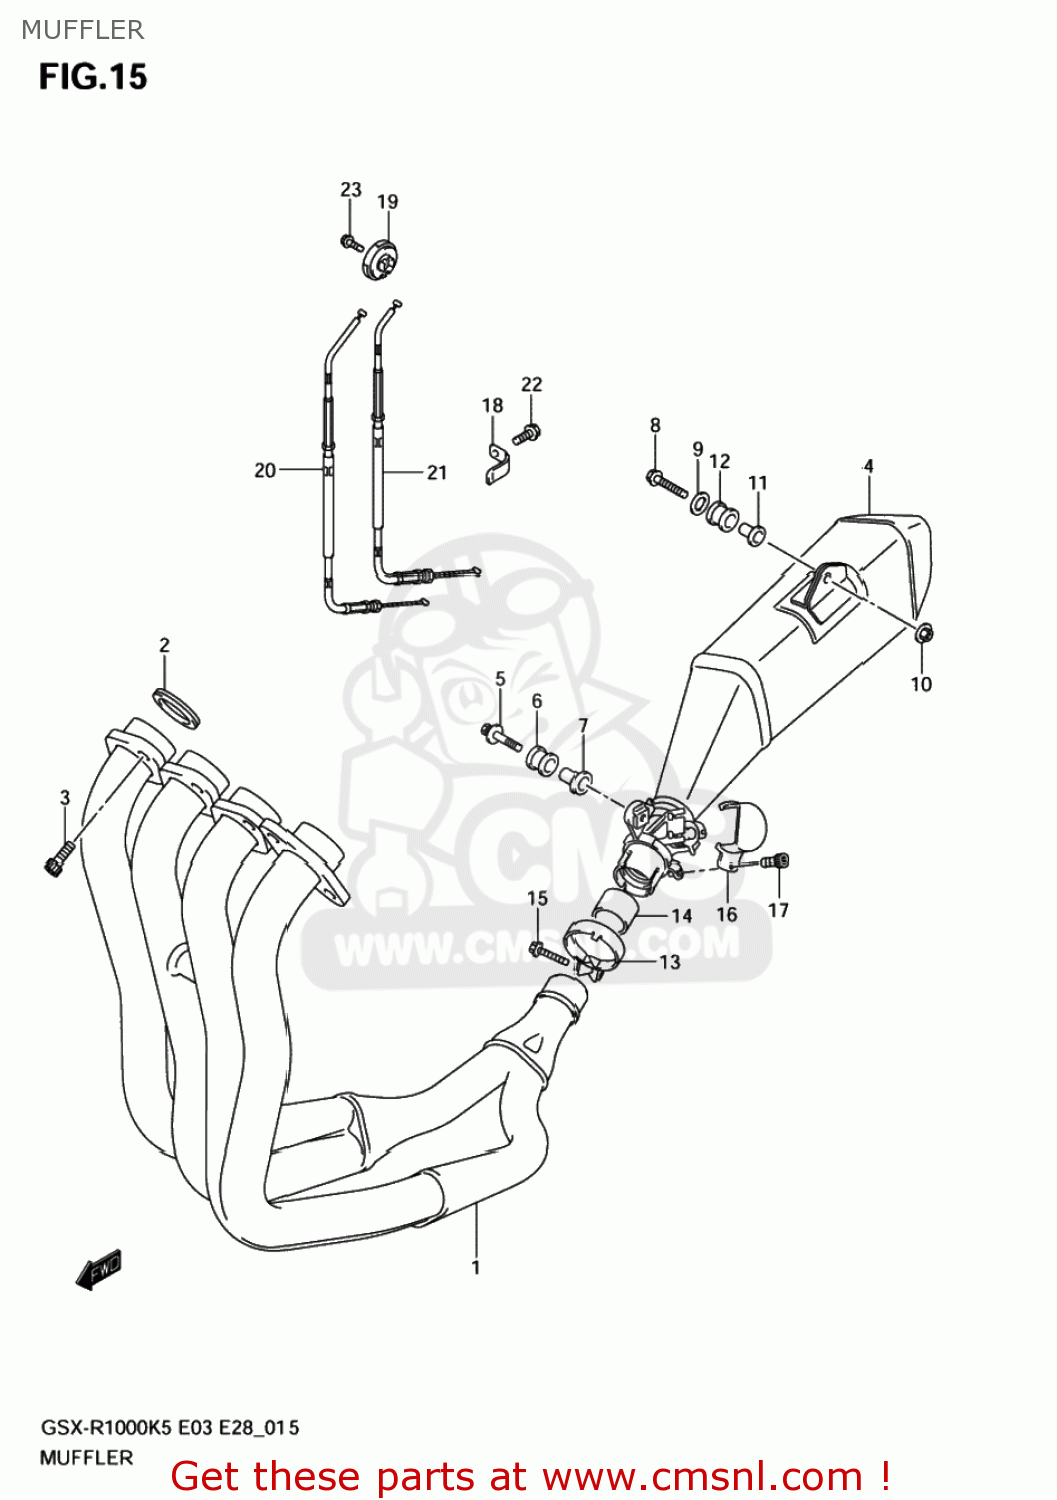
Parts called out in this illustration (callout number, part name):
1	EXHAUST
2	GASKET,EXHAUST PIPE
3	BOLT
4	BODY,MUFFLER
5	BOLT 8X45
6	CUSHION
7	SPACER(8.6X12X24.2)
8	BOLT(8X45)
9	WASHER(8.5X28X1.5)
10	NUT
11	SPACER(8.6X12X24.2)
12	CUSHION
13	CLAMP,CONNECTOR
14	CONNECTOR,MUF
15	BOLT
16	COVER,EXHAUST,VALVE
17	BOLT(6X12)
18	BRACKET,EXHAUST VALVE CABLE
19	PULLEY CONTROL
20	CABLE,EXHAUST VALVE NO.1
21	CABLE,EXHAUST VALVE NO.2
22	BOLT
23	BOLT
